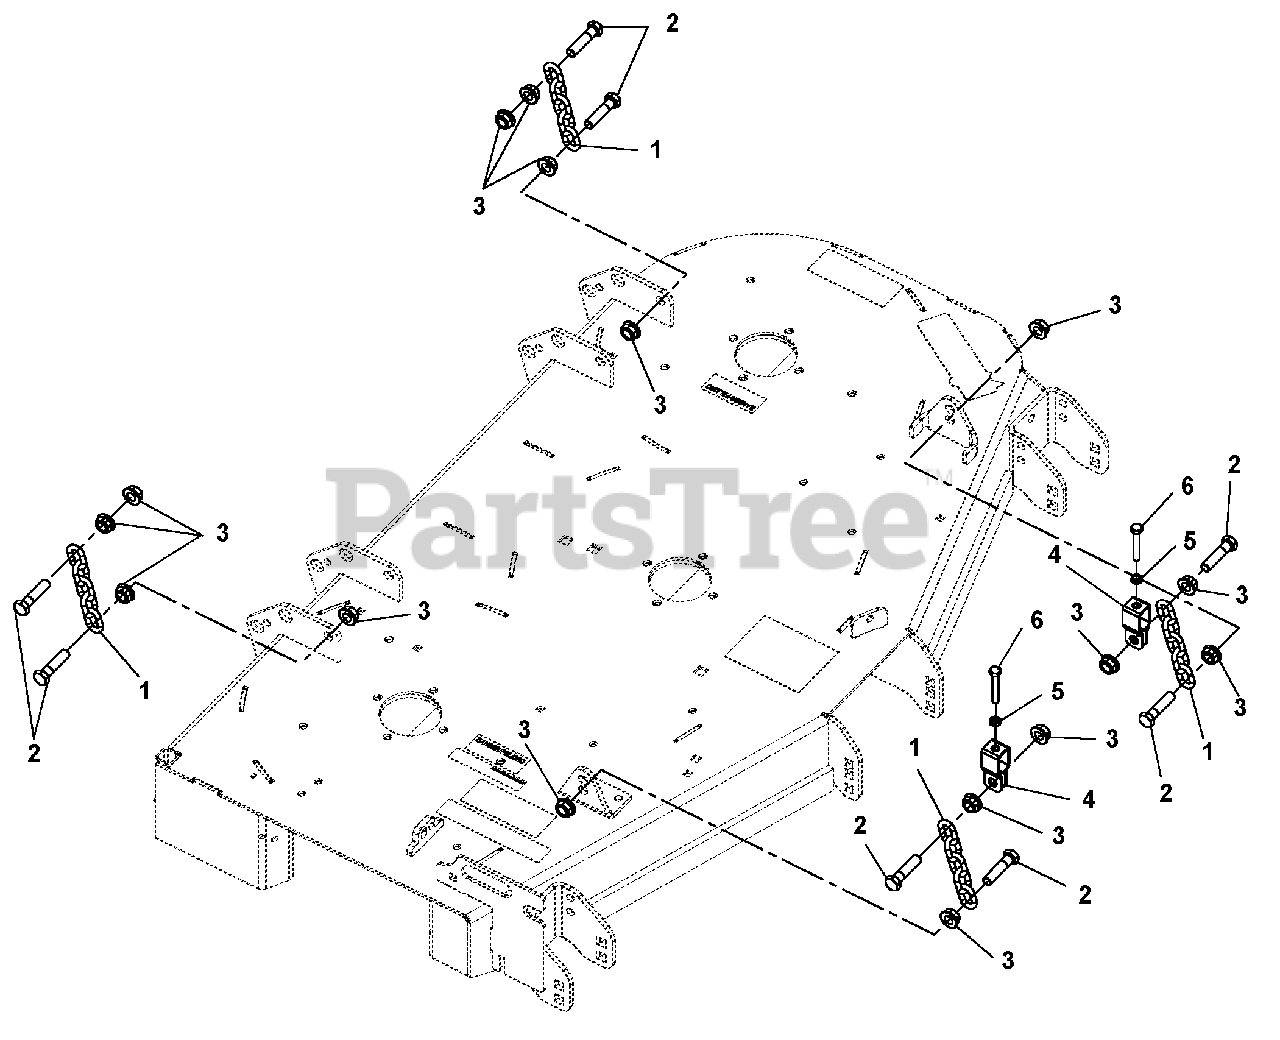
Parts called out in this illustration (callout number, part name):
1	CHAIN, LINK
2	BLT, HEX M12-1.75X50 CLS8.8 YZ
3	NUT-SPNLK-FLG M12-1.75 YZ
4	BRKT, DECK LEVELING
5	NUT- JAM .312-18 YWZC
6	BLT-HEX .312-18X2.00 FTH GR5YZ
